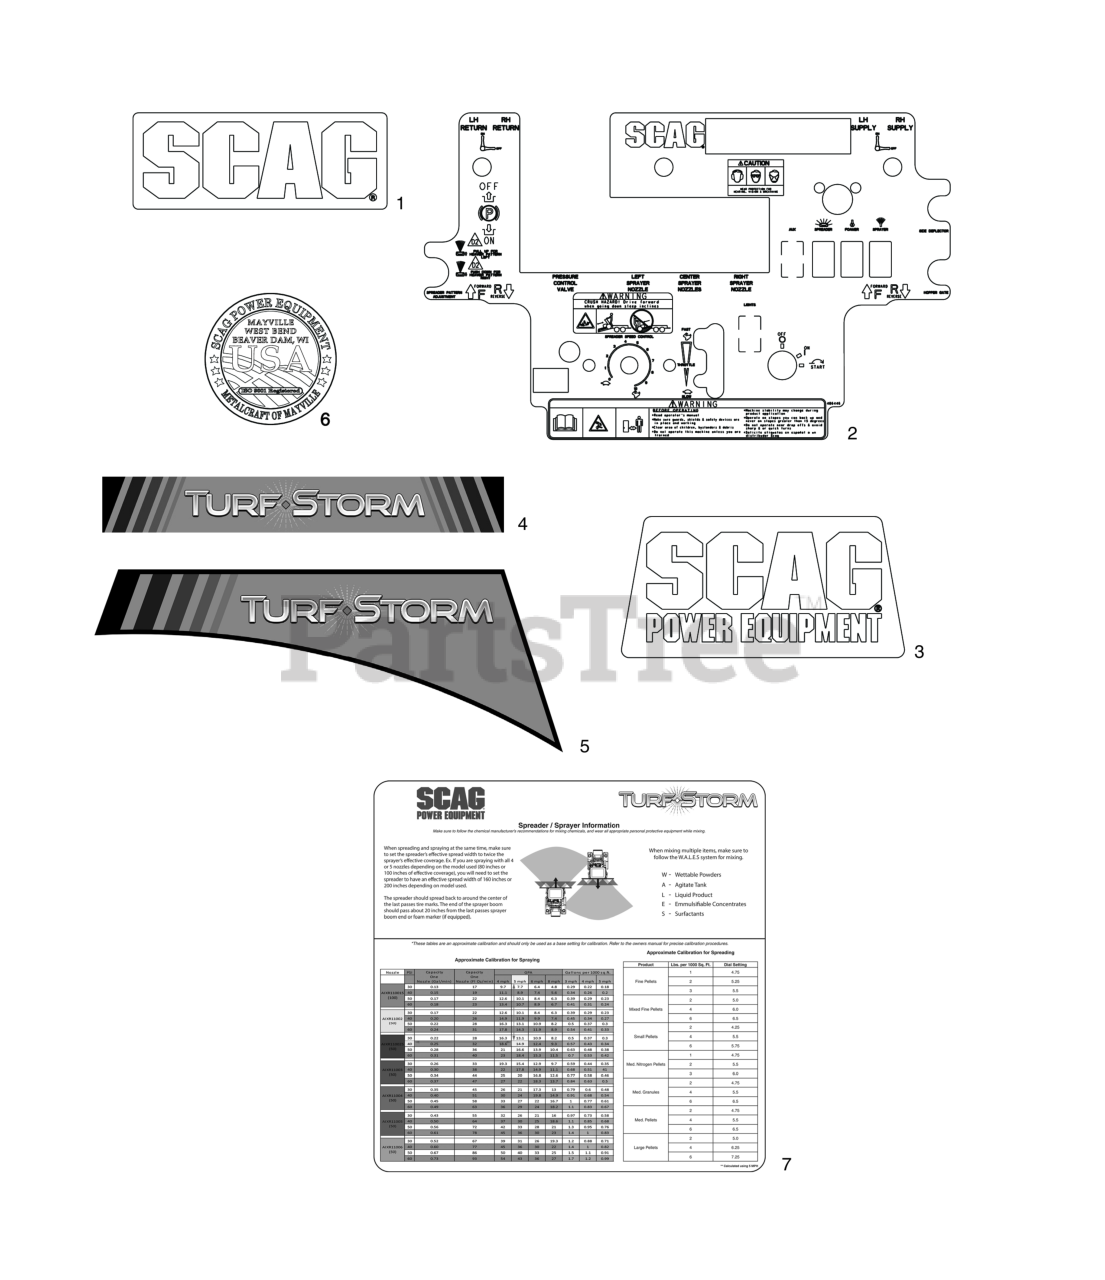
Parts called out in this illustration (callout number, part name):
1	Decal, Scag - Fuel Tank
2	Decal, Instrument Panel - Turf Storm
3	Decal, Scag Power Equipment (Fuel Tank)
4	Decal, Hopper Front - Turf Storm
5	Decal, LH Spray Tank - Turf Storm
6	Decal, Metalcraft - USA
7	Decal, Stray & Spread Instructions - Turf Storm
